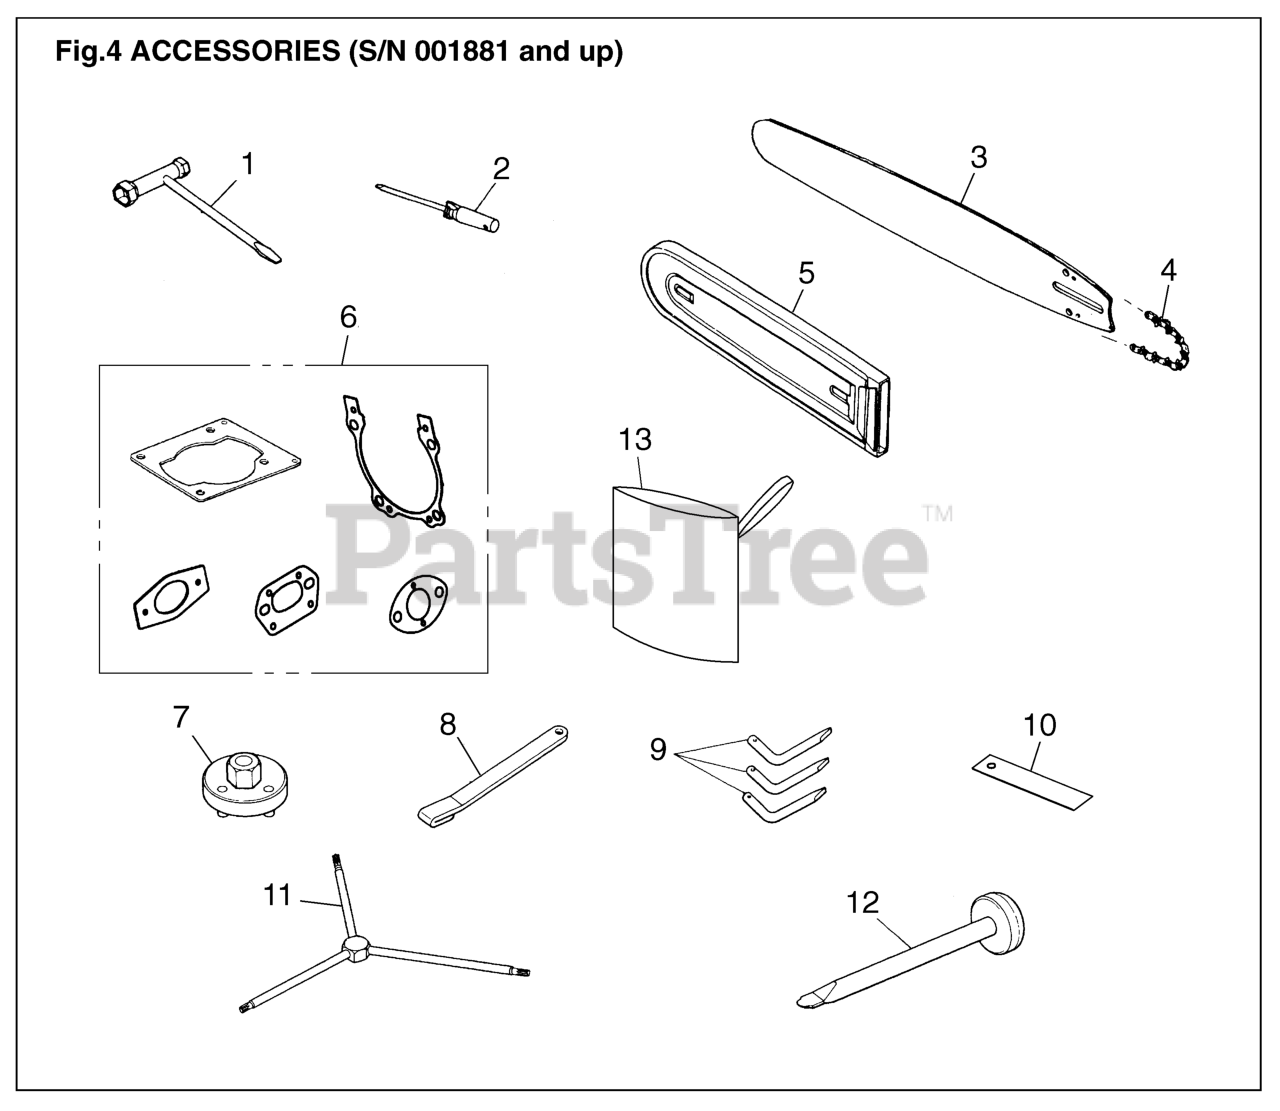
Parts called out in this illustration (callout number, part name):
3	BAR 16"(FITS:G3800 & GZ4000)
4	CHAIN (16") FOR G3800 GZ4000
6	KIT, GASKET (G3800AVS)
